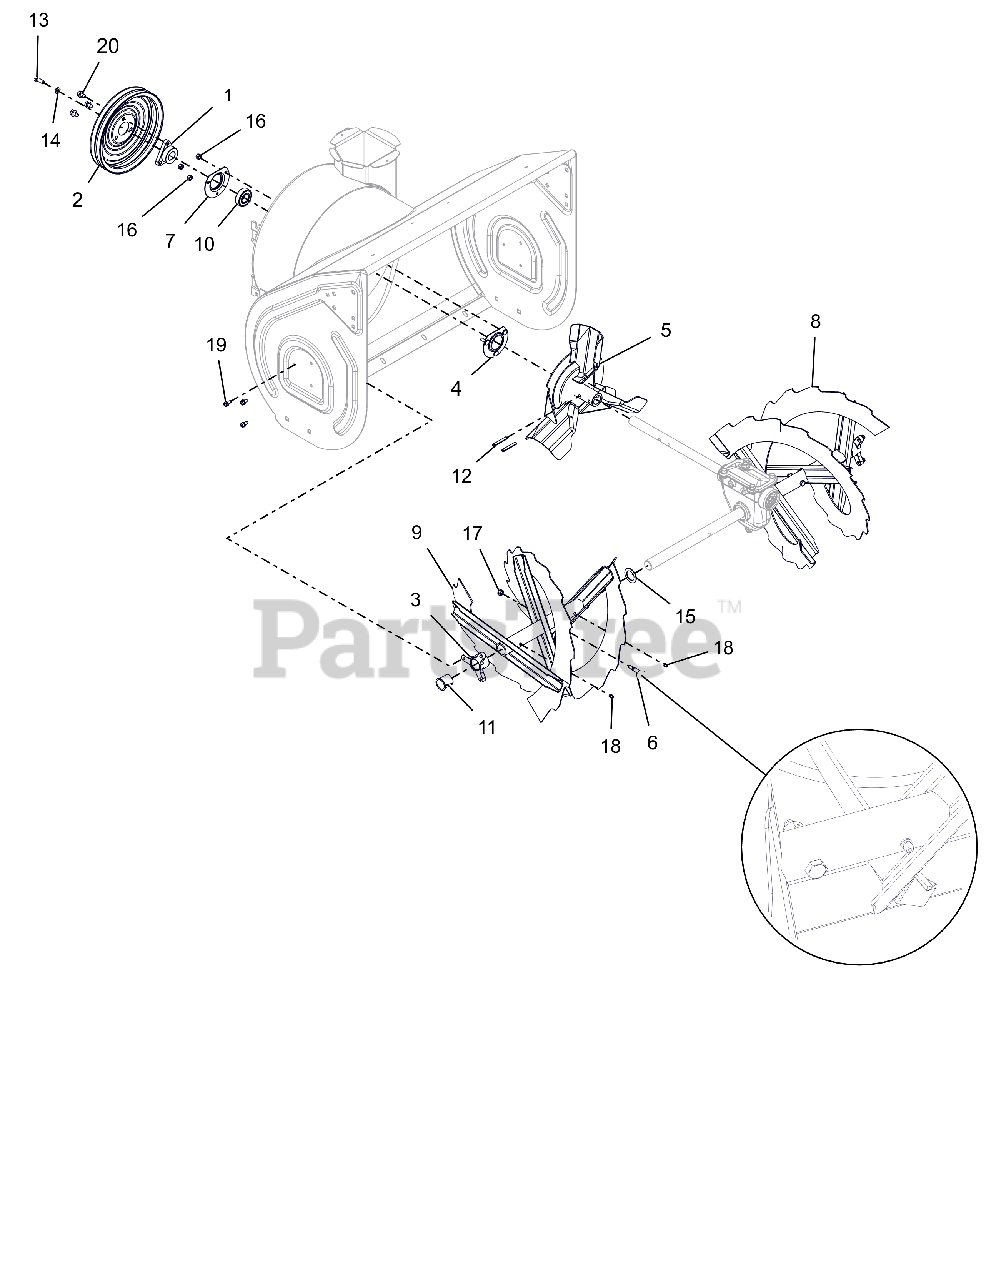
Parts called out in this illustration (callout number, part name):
1	PULLEY HUB, D-BORE .87 PRO
2	PULLEY, SPIN FORM DUAL GROOVE
3	BUSHING, RAKE SHAFT 1"
4	BEARING FLANGE
5	IMPELLER, 3 BLADE-14"
6	BOLT, SHEAR - DELUXE
7	BEARING FLANGE
8	RAKE, LH-28"(1 ID X 15.75 OD)
9	RAKE, RH-28"(1 ID X 15.75 OD)
10	BRG-BALL .876X1.75X.50 RSTFP
11	BSHG-FLG SPLIT NYLINER 1.0" HP
12	PIN-ROLL .250X1.75
13	BLT-HEX .31-24X.75 YWZC GR5
14	WSHR-LK .312X.097 HVY YWZC
15	WSHR-FL-STL 1.010X1.505X.062YZ
16	@NUT-LK-CTR .25-20 YWZC
17	@NUT-LK-CTR .31-18 YWZC
18	ZERK,FITTING .25X.125 DRIVE IN
19	SCR-TAP .25-20X.50 HWH TR YWZ
20	@SCR-TAP .31-18X.50 HWH TR YWZ
